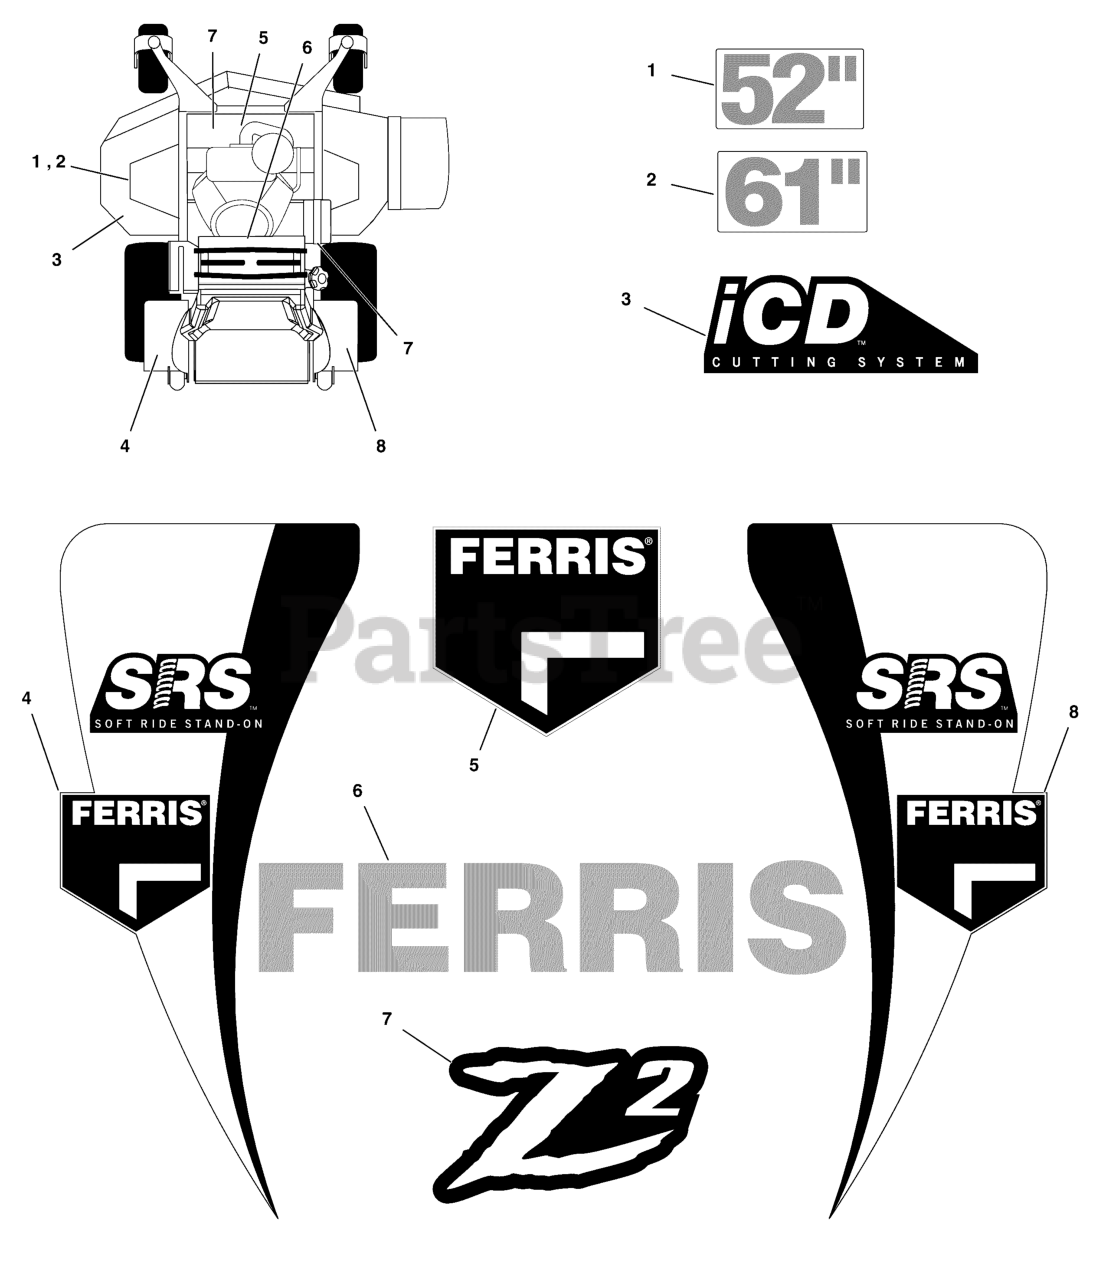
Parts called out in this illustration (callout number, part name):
1	DECAL, 52
2	DECAL, 61"
3	DECAL, iCD CUTTING SYSTEM
4	DECAL, FENDER, SRSZ1 / Z2, LH
5	DECAL, FERRIS LOGO, MEDIUM
6	DECAL, FERRIS, 2.23" X 11.39"
7	DECAL, MODEL, Z2
8	DECAL, FENDER, SRSZ1 / Z2, RH
